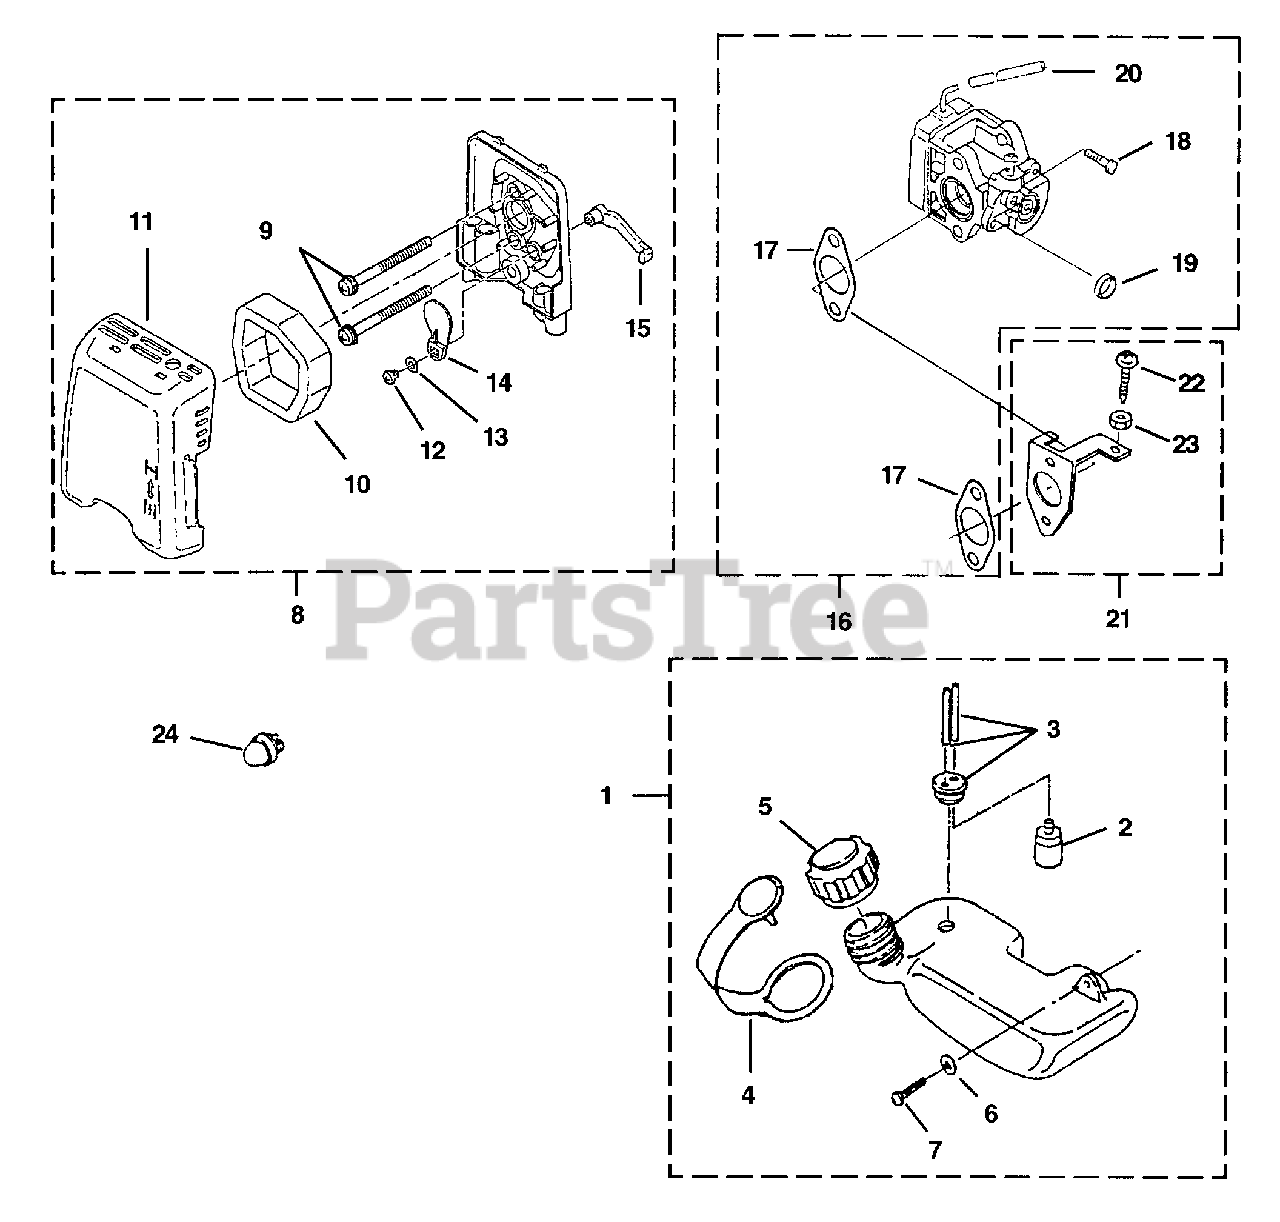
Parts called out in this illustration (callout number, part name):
1	FUEL TANK ASSEMBLY
2	FILTER-Fuel
4	CAP-Retainer
5	CAP-Fuel
6	WASHER (M5)
7	SCREW-Tapping (M5 x 20)
8	AIR FILTER ASSEMBLY
9	SCREW (M5 x 62)
10	FILTER-Air
11	COVER-Air Filter
12	SCREW, Tapping (M4 x 8)
14	CHOKE PLATE
15	CHOKE LEVER
16	CARBURETOR ASSEMBLY
17	GASKET-Carburetor
18	SCREW-Collar Throttle
19	HOLDER-Throttle Cable
20	LINE-Fuel
21	CABLE BRACKET ASSEMBLY
22	SCREW-Cone Point
23	NUT-Cable Adjust
24	PRIMER BULB
